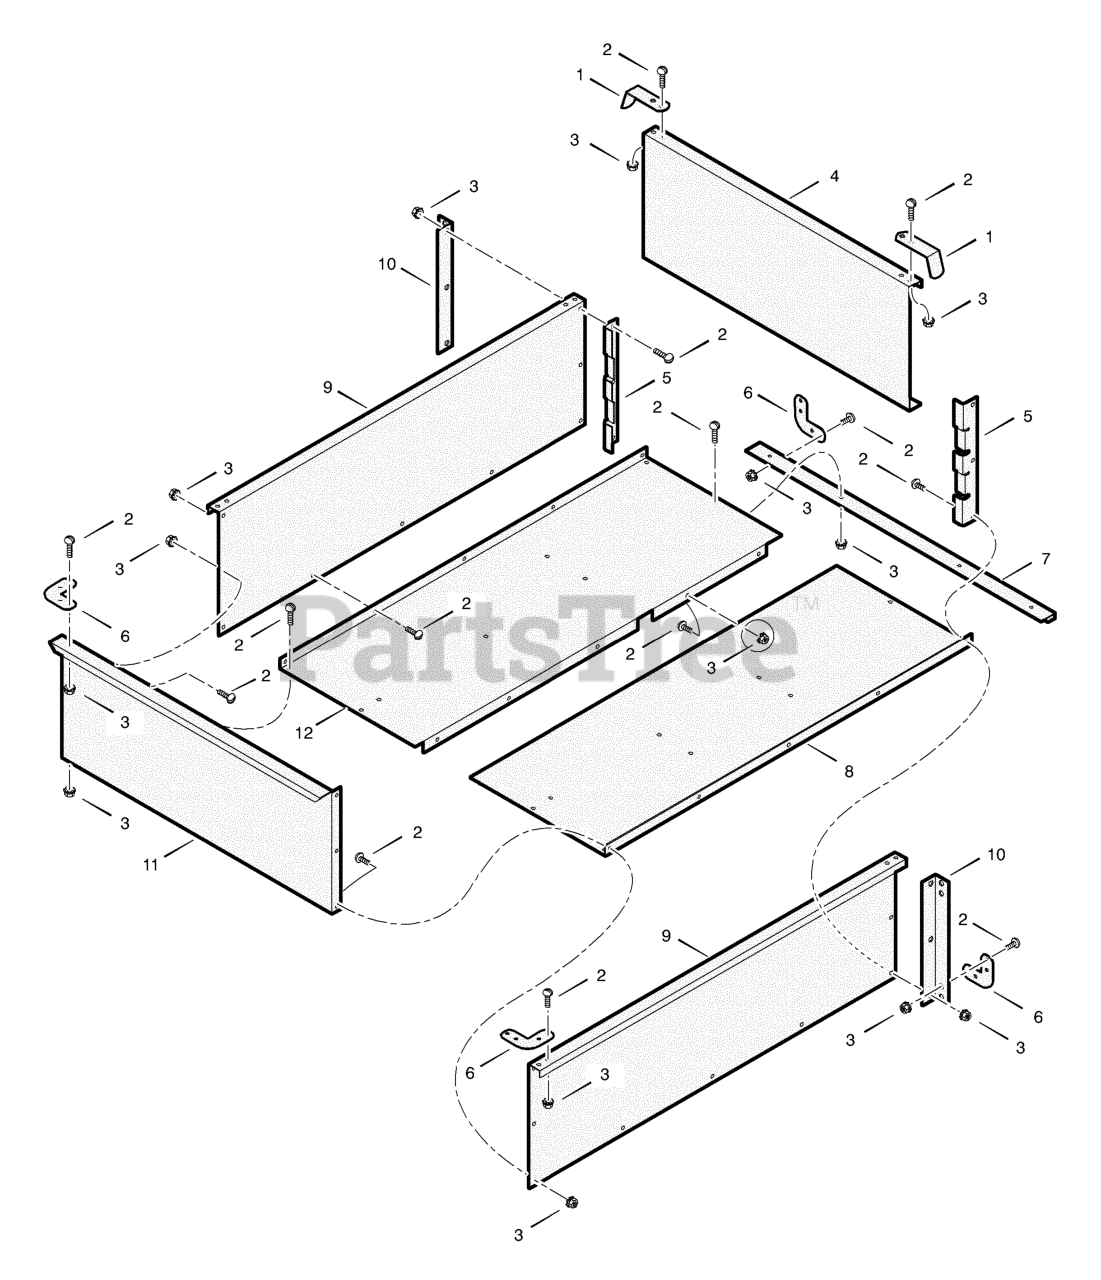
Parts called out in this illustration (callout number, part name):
1	Support, Side
2	Screw 1/4-20x0.50
3	Nut, Keps 1/4-20
5	Retainer, Tailgate
6	Bracket, Corner
7	Brace, Rear
8	Bottom, Left
9	Panel, Side
10	Support, Side
11	Panel, Front
12	Bottom, Right
